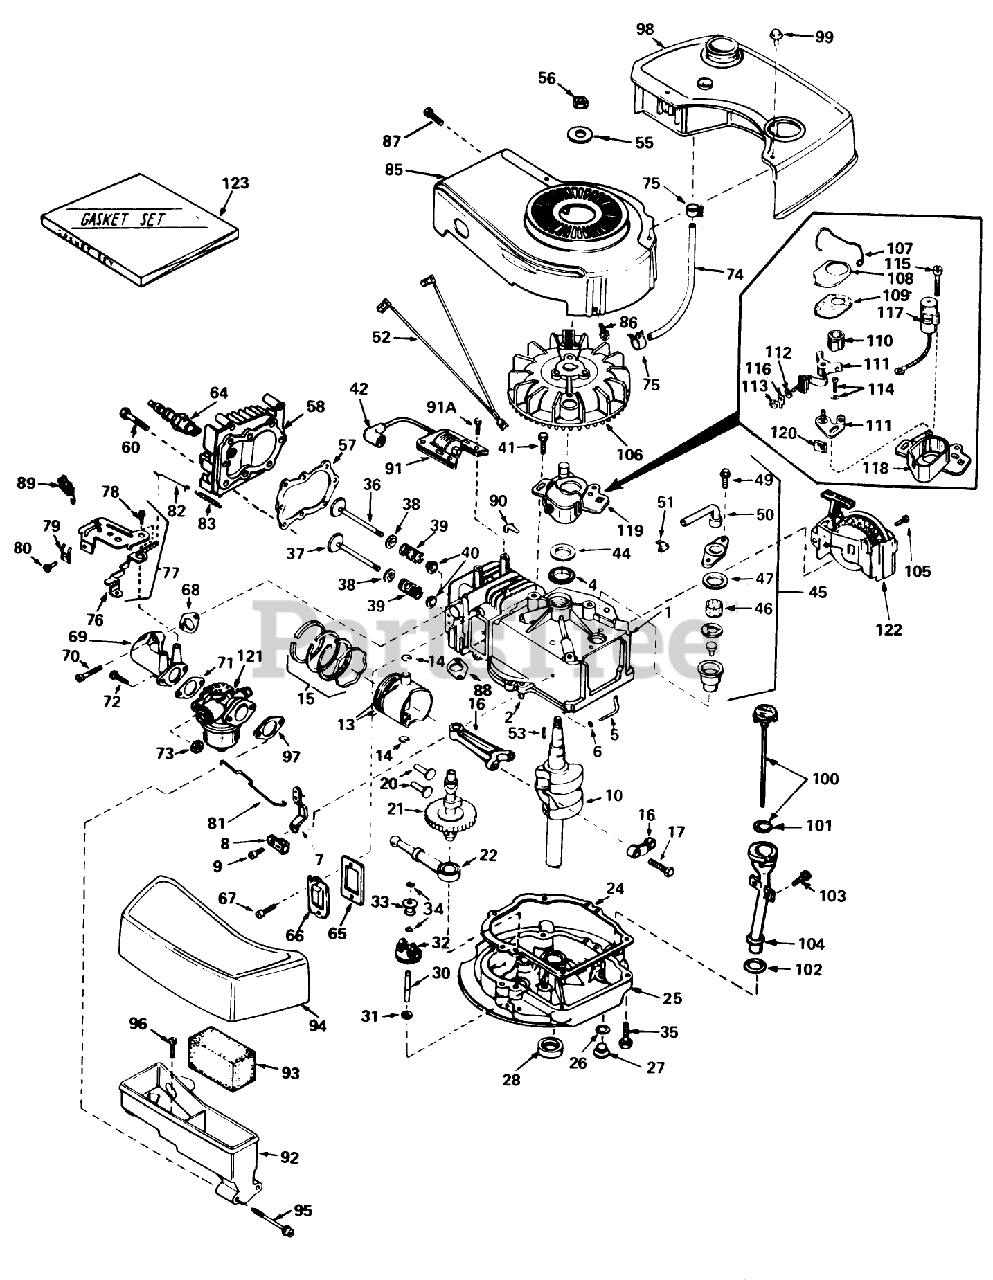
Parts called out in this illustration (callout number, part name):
1	Cyiinder Assy. (Incl. Ref. #2, 4 105)
2	Pin-Dowel
4	Seal-Oil
5	Rod, Governor (Incl. No. 36)
6	Washer-Flat
7	Governor Lever
8	Clamp-Lever, Governor
9	Screw
10	Crankshaft
13	Piston Pin Assy. (Incl . Ref. . #14) (Std.)
13	Piston, Pin Ring Assy. (Std.)(Incl. Ref. #13A, 14 15)
13	Piston Pin Assy. (Incl. Ref. #14) (.010 Oversize)
13	Piston,Pin Ring Assy. (.010 over-size)(Incl. Ref. #13A, 14 15)
13	Piston Pin Assy. (.020 oversize) (Incl. Ref. #14)
13	Piston, Pin Ring Assy. (Incl. Nos. 13A, 14 15)(.020 oversize)
14	Ring-Retaining, Piston Pin
15	Ring Set Piston (Std.)
15	Ring Set Piston (.010 Oversize)
15	Ring Set Piston (.020 Oversize)
16	Rod Assy., Connecting (Incl. Ref. #17)
17	Bolt-Rod, Connecting
20	Lifter-Valve
21	Camshaft(Mech.Comp. Release)
22	Oil Pump ASM
24	Gasket, Mounting
25	Flange Assy., Mounting (Incl. Ref. #26thru 30)
26	Gasket-Oil Drain
27	Plug Oil Drain
28	Seal Oil
30	Shaft-Governor
31	Washer-Flat
32	Governor Gear ASM
33	Spool-Governor
34	Ring-Retaining
35	Screw (1/4-20 x 1-1/4)
36	Valve, Intake (Incl. Ref. #38, 39 40) (Std.)
36	Valve, Exhaust (1/32" Oversize) (Incl. Nos. 8, 9 10)
37	Valve, Exhaust (Standard) (Incl. Nos. 8, 9 10)
37	Valve, Exhaust (1/32" Oversize) (Incl. Nos. 8, 9 10)
38	Cap-Upper Valve Spring
39	Spring-Valve
40	Cap-Valve, Spring
41	Screw
42	Cover-Spark Plug
44	Gasket Stator
45	Breather Assy. (Incl. Ref. #46, 47, 49, 50 51 )
46	Element-Breather
47	Gasket-Breather
49	Screw, Hex Hd. w/Conical
50	Tube, Breaker
51	Clip, Breather
52	Wire Ground
53	682488 LB GRASS HI-
55	Washer-Belleville
56	Nut-Flywheel
57	63573 GIL 42 SNWTHW
58	Head-Cylinder
60	Screw (5/16-18x1-1/2)
64	Plug, Spark (J17LM or equiv.)
64	Plug, Spark (Champion RCJ-8)
65	Gasket-Breather
66	Cover-Valve
67	Screw
68	Gasket, Intake
69	Pipe, Intake
70	Screw (1/4-20 x 1)
71	Gasket-Carburetor
73	Nut and Lock Washer (1/4-28)
74	Line-Fuel
75	Clamp-Line, Fuel
76	Lever Control
77	Control Assy., Speed (Incl. Nos, 76, 78 89)
78	Screw, Hex Washer Hd Shoulder Self-Tap
79	Conduit
80	Screw (10-32 x 3/8)
81	Link-Throttle
82	Link Governor Spring
83	Spring Governor
85	Housing Blower
86	Screw
87	Screw (10-24 x 9/16)
88	Gasket Exhaust
89	Terminal
90	Clip-Wire
91	Lamination Coil Assy. (Incl. No. 42)
91A	Screw
92	Body Air Cleaner
93	Filer, Air
94	Cove, Air Cleaner
95	Screw Fil Hd.
96	Screw, Hex Hd.
97	Gasket-Air Cleaner
98	Tank, Fuel
99	Screw (10-32 x 35/64)
100	Dipstick, Oil (Incl. Ref. #101)(Twist Lock)
101	O-Ring
102	Gasket
103	Screw (10-32 x 1/2)
104	Tube-Oil Fill
105	Screw (1/2-20x5/8)
106	FIywheel
107	Spring Breaker Box
108	Cover-Dust
109	Gasket-Dust Cover
110	Cam-Breaker
111	Breaker Assy.
112	Washer
113	DECAL
114	Breaker Screw
115	Condenser Screw
116	Terminal, Ground
117	Condenser
118	Stator Plate
119	Stator Plate Assy. (incl. Nos. 107, 111 thru 118 120)
120	Felt,Cam Wiper
121	Carburetor (Incl. Ref. #71 )
122	Starter-Sidemount
123	53024/VAR.16HP O/P
